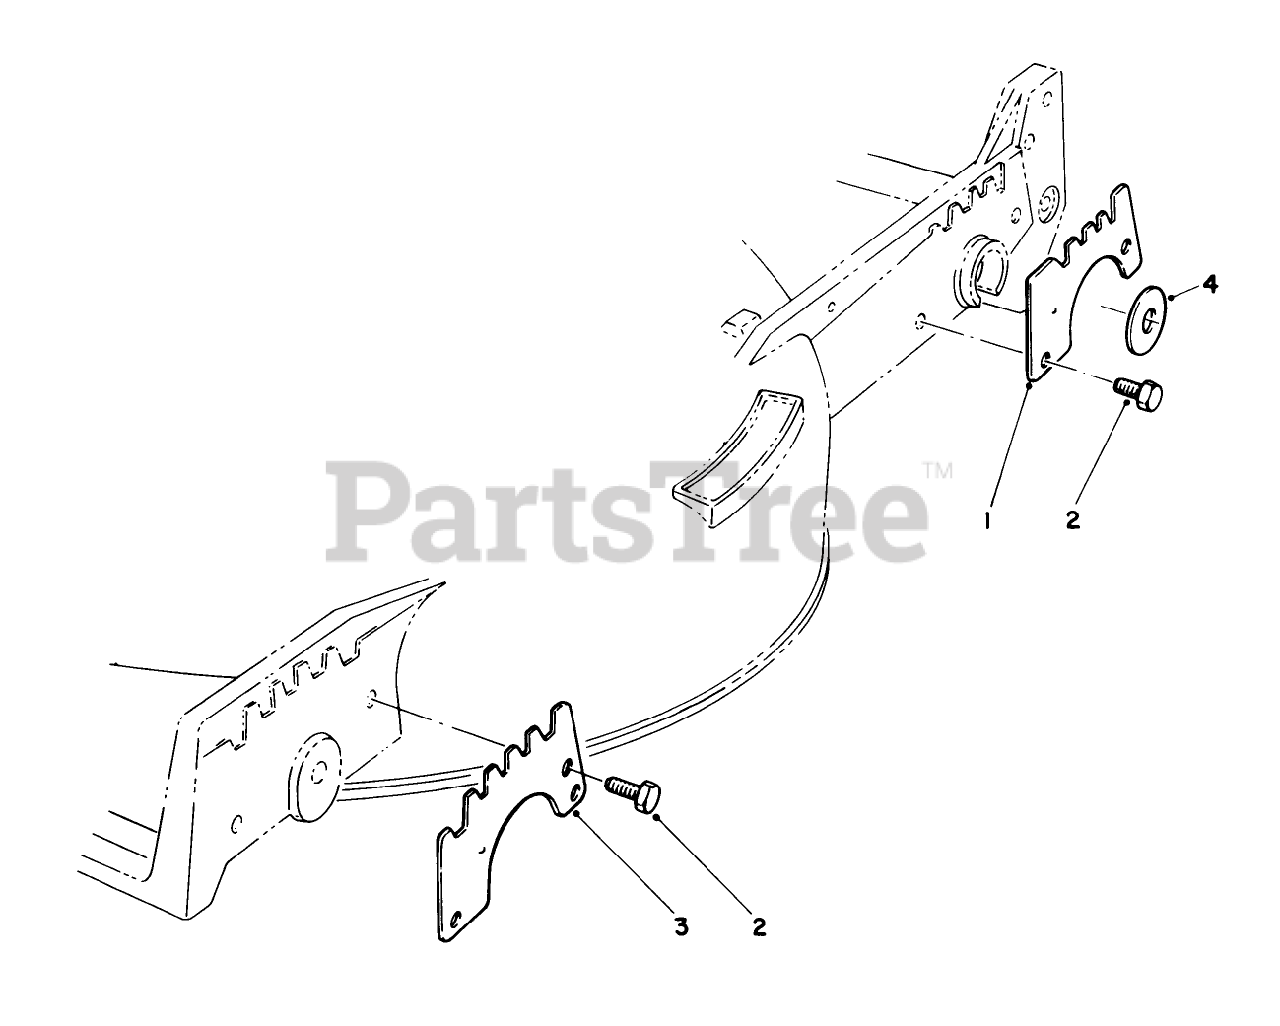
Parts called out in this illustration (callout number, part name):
1	WEAR PLATE,REAR
2	SCREW-HWH
3	WEAR PLATE
4	PIVOT WASHER
